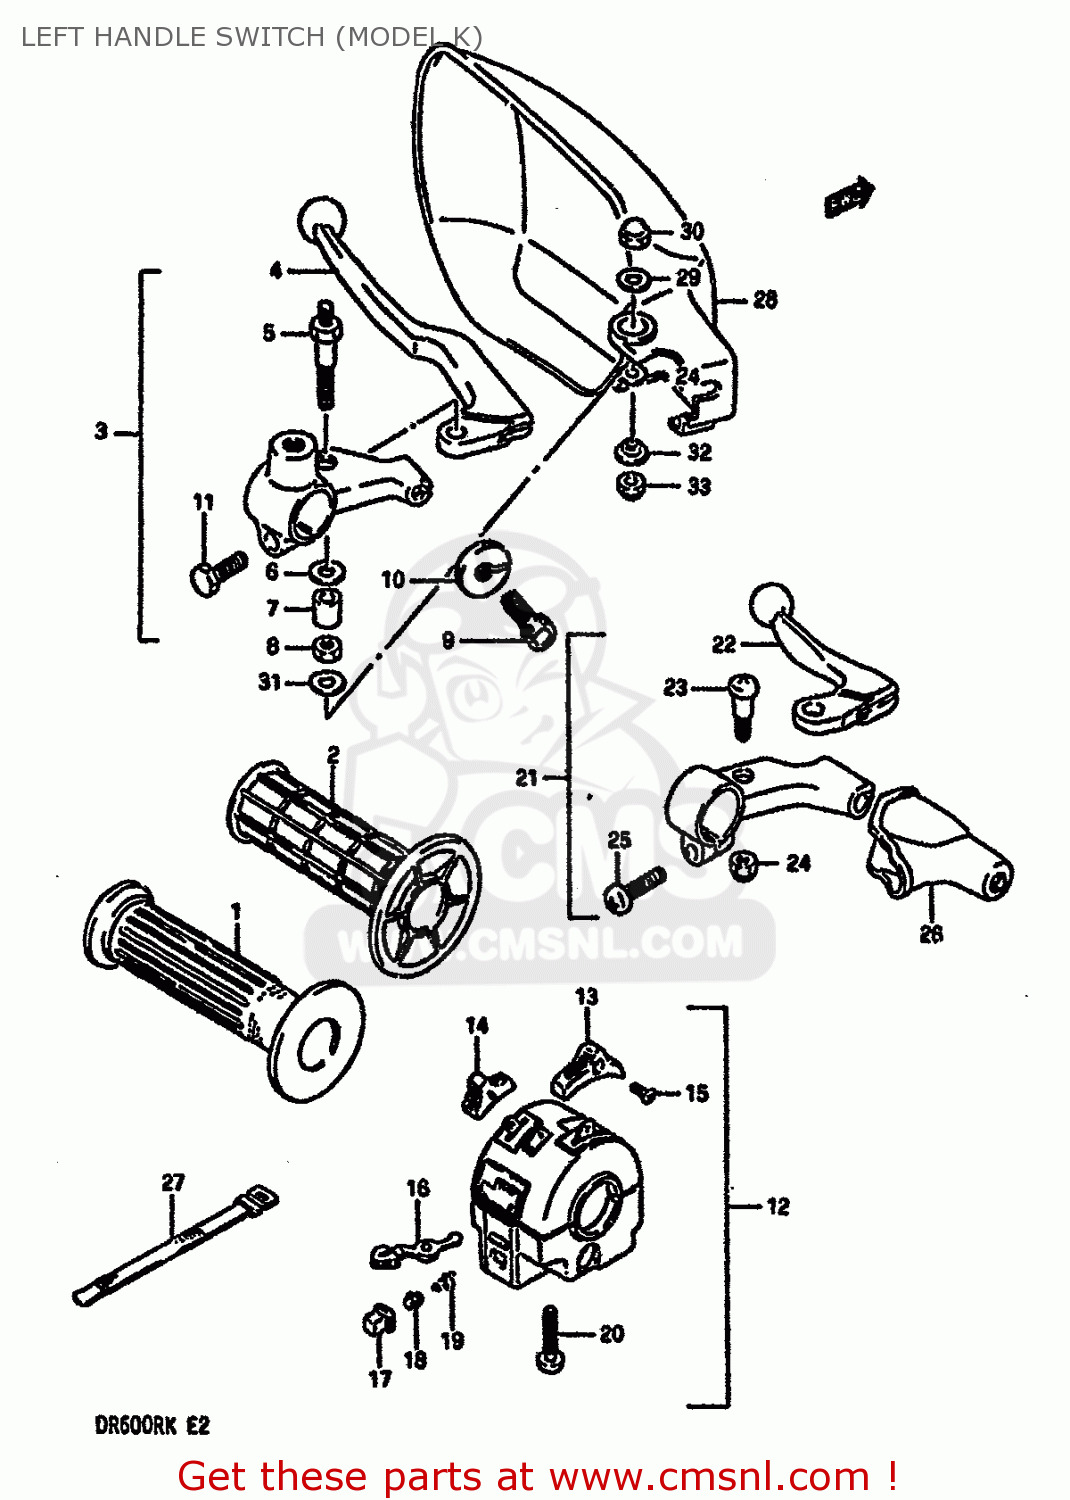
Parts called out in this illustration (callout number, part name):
1	GRIP,L
2	GRIP,LEFT
3	LEVER ASSY,CLUTCH
4	LEVER,CLUTCH
5	BOLT,LEVER SET
6	WASHER,LEVER SET
7	SPACER,LEVER SET
8	NUT
9	ADJUSTER,CABLE
10	NUT,CABLE ADJUSTER LOCK
11	BOLT
12	SWITCH ASSY,HANDLE,LH
13	KNOB,LIGHTING SWITCH
14	KNOB,DIMMER SWITCH
15	SCREW
16	KNOB,TURNSIGNAL
17	BUTTON,HORN
18	CONTACT
19	SPRING
20	SCREW
21	LEVER ASSEMBLY,DECOMPRESSION
22	LEVER,DECOMP
23	BOLT,LEVER
24	NUT
25	SCREW
26	COVER,DECOMP LEVER DUST
27	CLAMP(L:120)
28	COVER,KNUCKLE,LH (WHITE)
29	WASHER (6.5X20X1.6)
30	NUT 6MM
31	WASHER(6.5X16X1.2)
32	WASHER
33	NUT 6MM
